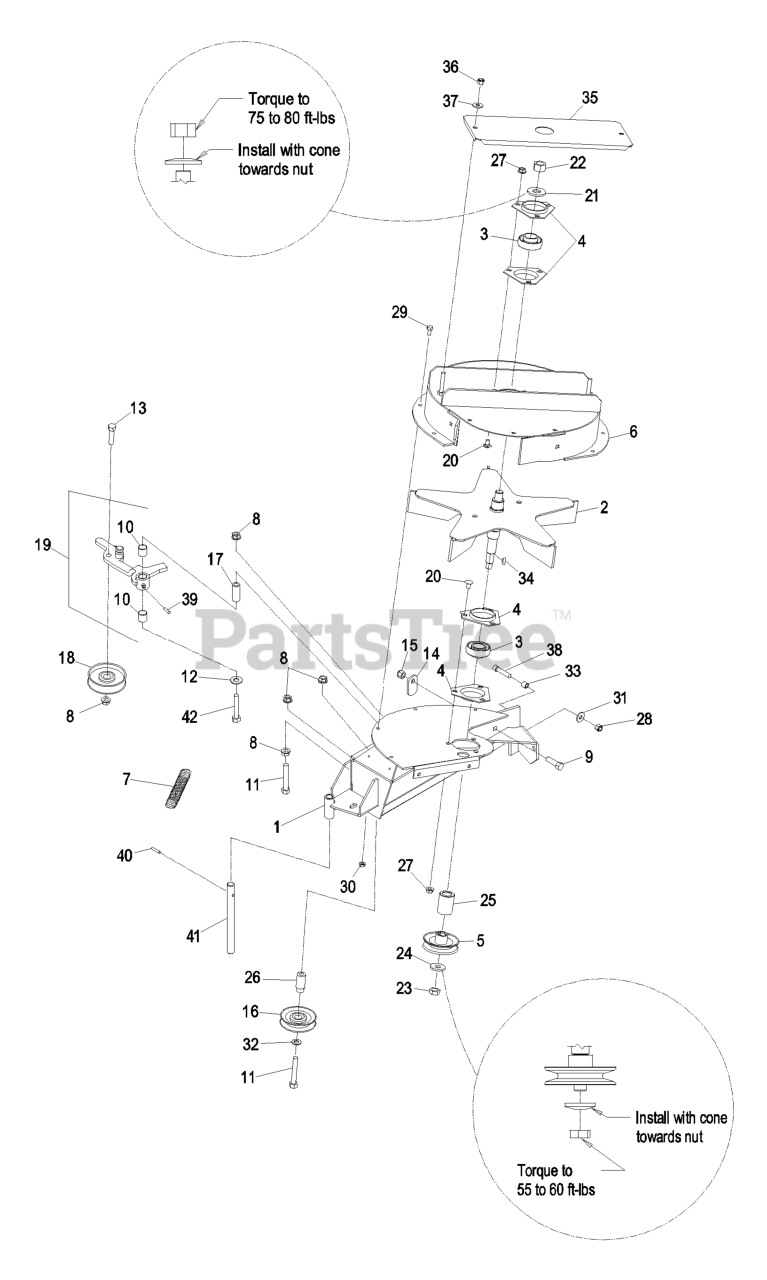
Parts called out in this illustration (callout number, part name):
1	WLD, BLOWER MOUNT
2	IMPELLER
3	BEARING
4	HOUSING-FLANGE
5	SHEAVE-BLOWER
6	ASM,UPPER HOUSING
7	SPRING-IDLER
8	NUT-HHF, WHIZ
9	SCREW-HH
10	BUSHING
11	BOLT-CARR
12	WASHER-FLAT
13	SCREW-HH
14	LATCH-CATCHER, GRASS
15	NUT-LOCK, NI
16	IDLER-INSIDE
17	BUSHING-PIVOT, IDLER
18	IDLER-FLAT
19	ASM, IDLER ARM - SERVICE
20	SCREW-CARR
21	WASHER-SPRING
22	NUT-HEX
23	NUT-JAM
24	WASHER-SPRING
28	NUT-HEX
29	SCREW-HH
31	WASHER-SPRING
32	WASHER-FLAT
33	BUSHING, LOCATOR
34	KEY-WOODRUFF
35	ASM, BEARING COVER
36	NUT-LOCK, NI
37	WASHER-FLAT
38	SCREW-HSH
39	FITTING-GREASE
40	PIN-ROLL
41	SHAFT-CATCHER, GRASS
42	SCREW-HSBH
